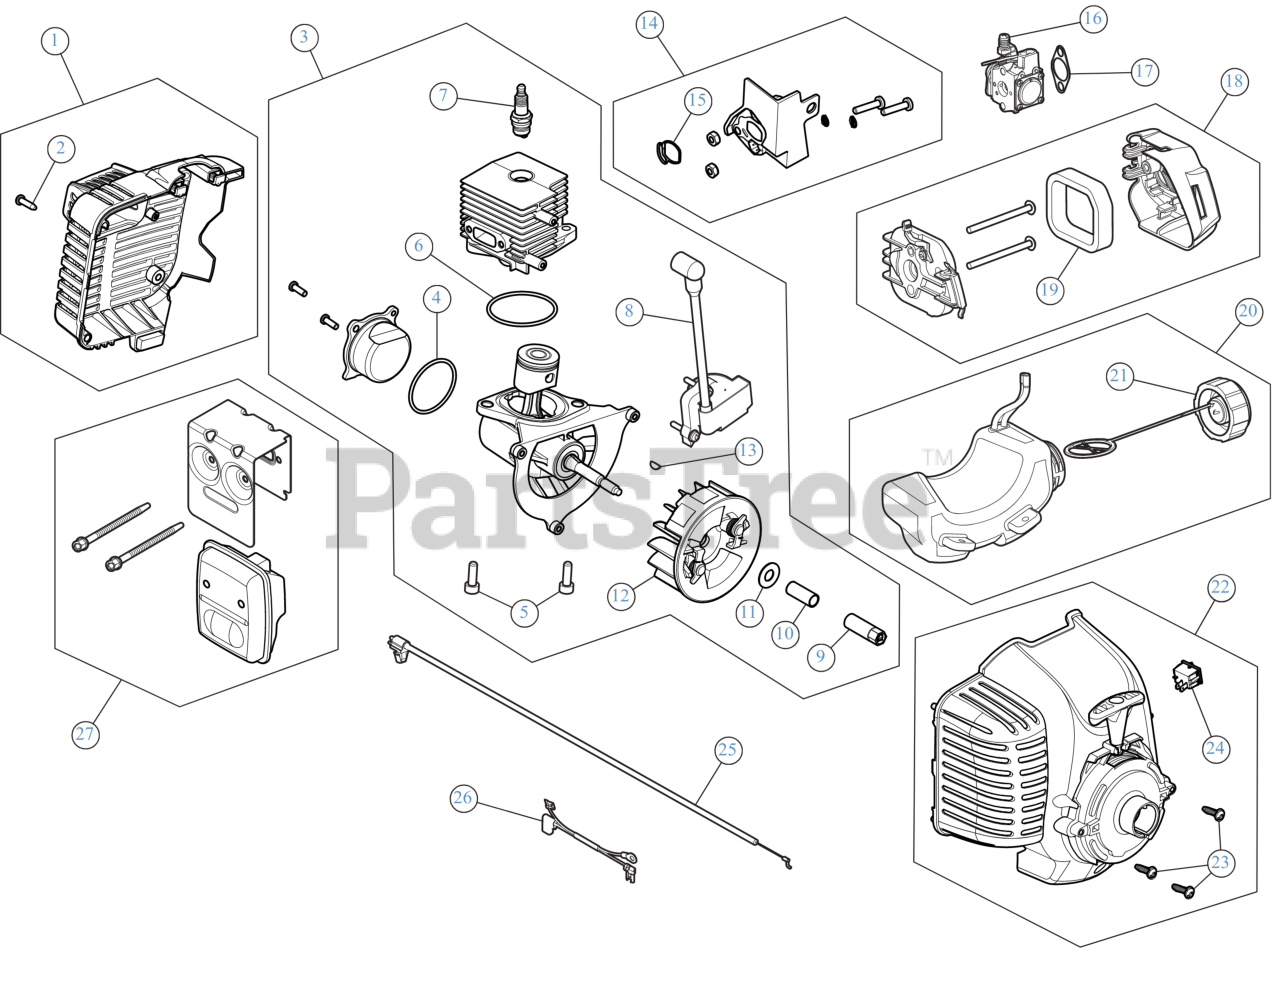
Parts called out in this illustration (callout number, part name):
1	HOUSING ASSEMBLY RR
2	SCREW, #8-16X.750 PH
3	SHORT BLOCK
4	O-RING SEAL CRANKCASE
5	SCREW 5/16-18x3/4 T40
6	O-RING SEAL CYLINDER
7	SPARK PLUG
8	MODULE ASSEMBLY
9	POWER SHAFT ADAPTER
10	SPACER CRANKSHAFT
11	BELL WASHER
12	FLYWHEEL ASSEMBLY
13	WOODRUFF KEY #403-.125 x .375
14	INTAKE ASSEMBLY
15	INSL/CYL SEAL
16	CARBURETOR
17	GASKET CARB
18	AIR CLEANER
19	AIR FLITER
20	FUEL TANK ASSEMBLY
21	FUEL CAP ASSEMBLY
22	STARTER HOUSING
23	SCREW #
24	SW, MOMENTARY ON/O
25	THROTTLE CABLE
26	SHORT WIRE LEAD
27	MUFFLER ASSEMBLY
